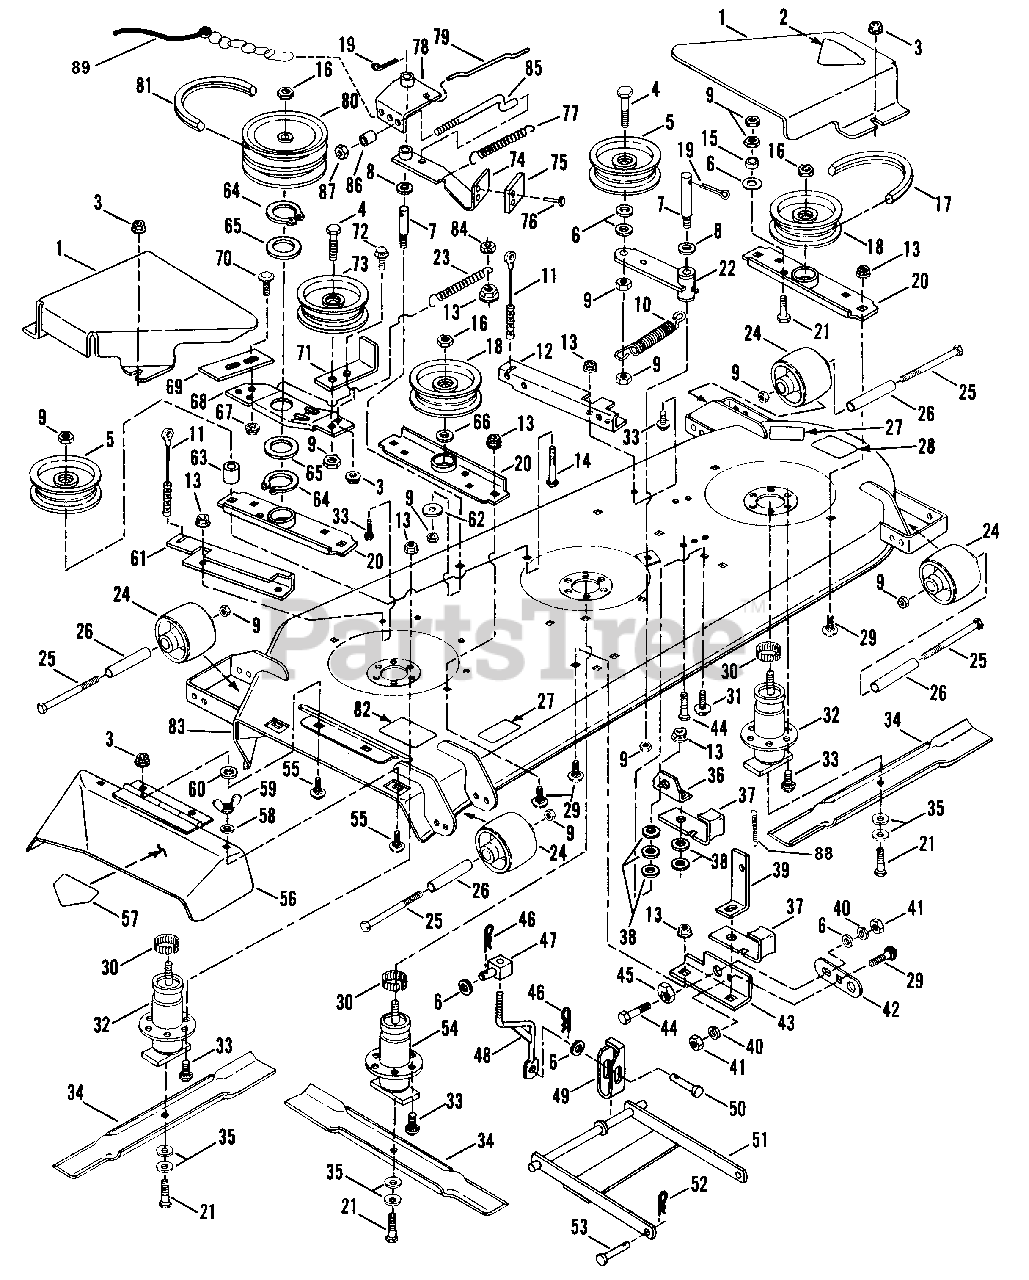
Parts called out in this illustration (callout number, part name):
1	GUARD, Pulley
2	DECAL, 48" Deck
3	NUT, 5/16-18 Hex Flange Lock
4	SCREW, 3/8-24 x 2" Hex Head Cap
5	PULLEY, Idler 4-1/2" O.D.
6	WASHER, 3/8" Flat
7	STUD, Idler
8	WASHER, 5/8 Flat
9	NUT, 3/8-24 Hex Lock
10	SPRING
11	CABLE, Support (4.75", 8 Spacers)
12	SUPPORT, Cable (Left Side - Rear)
13	NUT, 3/8-16 Hex Flange Lock
14	SCREW, 3/8-24 x 2-1/2" Hex Cap
15	SPACER, .623 OD X .380 ID X .250 L
16	NUT, 3/4-16 Hex Jam Lock
17	BELT, AA 107" EL
18	PULLEY, 4-3/4" O.D.
19	PIN, 1/8 x 1" Cotter
20	BRACE, Spindle
21	SCREW, 3/8-24 x 1-1/4" Hex Cap
22	ASSEMBLY, Idler Arm
23	SPRING, Idler Arm Weldment
24	WHEEL, Gage
25	SCREW, 3/8-24 x 3-3/4" Hex Cap
26	SPACER, .625 OD X .435 ID X 3 L YZ
27	PAD, Foot
28	DECAL, Caution
29	BOLT, 3/8-16 x 3/4" Carriage
30	RING, Tolerance 2.0"
31	BOLT, 3/8-16 x 1" Hex Flange Lock
32	ASSEMBLY, Spindle (Outboard)
33	BOLT, 3/8-16 x 3/4" Hex Fig. Lock
34	BLADE 16.5"
35	WASHER, 13/32x1-13/32" Dia. Cone
36	BRACKET, Front Hanger (Left Side)
37	BELT Guide (Yellow)
38	WASHER, 3/8" Flat
39	BRACKET, Spring
40	WASHER, 3/8 Split Lock
41	NUT, 318-16 Hex
42	LINK, Adjustment
43	BRACKET, Front Hanger (Left Side)
44	SCREW, 3/8-16 x 1" Hex Cap (Gr. 5)
45	RING, Adjustment
46	PIN, 3/32 x 1-19/32" Hair
47	SWIVEL, Front Lift Rod
48	ROD, Front Lift
49	HANGER, Front Lift
50	PIN, 3/8 x 1-1/2" Clevis
51	ASSEMBLY, Front Hanger
52	PIN, 5/32 x 2-5/8" Hair
53	PIN, 1/2 x 1-3/8" Clevis
54	ASSEMBLY, Spindle (Center)
55	BOLT, 5/16-18 x 5/8" Carriage
56	ASSEMBLY, Side Chute
57	DECAL, DANGER
58	WASHER, 5/16 Split Lock
59	NUT, 5/16-18 Wing
60	RETAINER, 5/16 Bolt
61	SUPPORT, Cable (Right Side - Rear)
62	GUIDE, Belt
63	SPACER, 1.00 OD X.39 ID X1.12 L
64	RING, 2" External Retaining
65	WASHER, Nylon
66	WASHER, 3/4 x 1-1/8" O.D. Flat
67	NUT, 1/4-20 Hex Flange Lock
68	WELDMENT, Idler Arm (Center)
69	STRIP, Brake
70	BOLT, 1/4-20 x 5/8" Carriage
71	GUIDE, Belt
72	BOLT, 5/16-18 x 3/4" Carriage
73	PULLEY, Flat Idler 4.12" OD
74	ASSEMBLY, Brake Weldment
75	LINER, Brake
76	RIVET, Brake Liner 3/16X1/2 ZP
77	SPRING, Brake Assembly
78	WELDMENT, Clutch Bracket
79	LINK, Clutch
80	PULLEY, Double
81	BELT, 48 Deck Drive HA 52.25
82	DECAL, Caution
83	DECK, 48" Mower
84	NUT, 3/8-16 Hex Center Lock
85	ROD, Brake Adjustment
86	SPACER, .5 OD X .258 ID X .75 L (No longer available, try using 7024114)
87	NUT, 1/4-20 Hex Center Lock
88	SPRING, Weight Transfer
89	"S" HOOK & CHAIN
